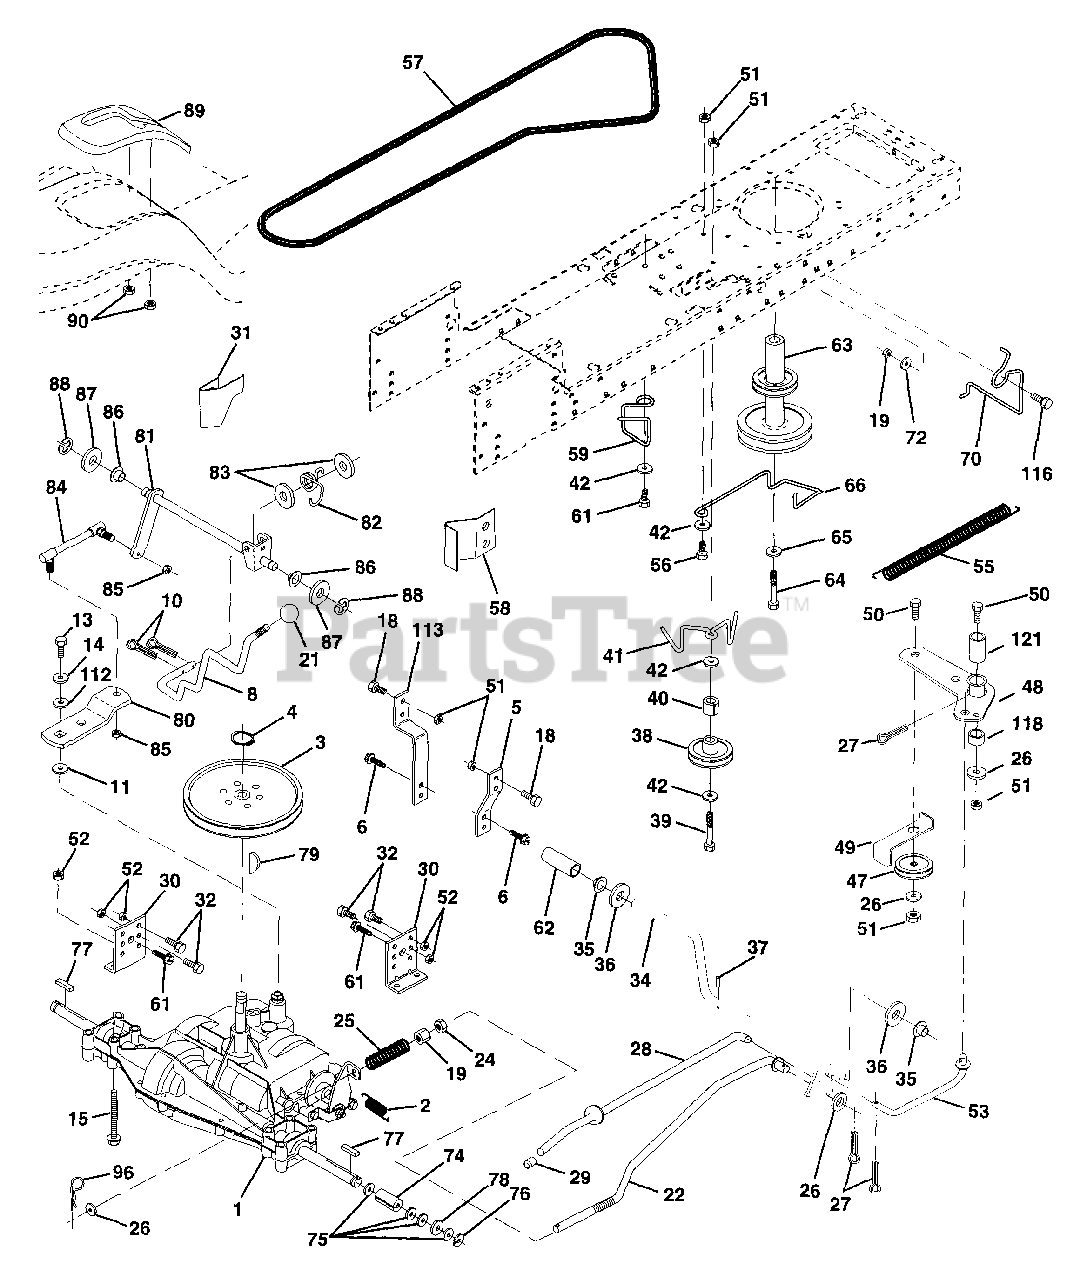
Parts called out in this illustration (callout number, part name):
2	Spring Return Brake T/a Zinc
3	Pulley Transaxle 18" tires
4	Ring Retainer # 5100-62
5	Strap Torque 30 Degrees
6	Screw Thdrol 5/1 6-18 X 3/4 TYT
8	Rod Shifter
10	Pin Cotter 1/8 X 1 Cad
11	Washer Plate Shf 388 Sq Hole
13	Bolt 1/4-28 Unf Gr 8 W/Patch
14	Washer Lock Hvy Helical 1/4
15	Bolt Hex 5/16-18 Gr. 5
18	Bolt, Fin Hex 3/8-16 UNC x 1 Gr. 5
19	Nut Lock 3/8-16 Unc
22	Rod Brake Blk Zinc 26 840
24	Nut Hex Jam 3/8-16 Unc
25	Spring Rod Brake 2 00 Zinc
26	Washer 13/32 X 13/16 X 16 Ga
27	Pin Cotter 1/8 X 3/4 Cad
28	Rod Brake Parking LT/YT
29	Cap Brake Parking Black
30	Bracket Mtg Transaxle
31	Keeper Belt LH LT 14 Ga
32	Bolt Hex Hd 5/16-18 unc X 3/4
34	Shaft Asm Pedal Foot
35	Bearing Nylon Blk 629 Id
36	Washer 21/32 X 1 X 16 Ga
37	Pin Roll 3/16 X 1"
38	Pulley Idler Flat
39	Bolt Fin Hex 3/8-16unc X 2-3/4
40	Spacer Split 395 X 59 Bzp
41	Keeper Belt Retainer Idler Foolproof
42	Washer 13/32 X 13/16 X 12 Ga
47	Pulley Idler V Groove Plastic
48	Bellcrank Asm
49	Retainer Belt Style Spring
50	Bolt Hex Hd 3/8-16unc X 1-1/2
51	Nut Crownlock 3/8-16 Unc
52	Nut Crownlock 5/16-18 Unc
53	Link Clutch
55	Spring Return Clutch 6 75
56	Bolt Fin Hx 3/8-16 X 1/4
57	V-Belt Ground Drive 95 25
58	Keeper Belt RH LT Pnt/zinc 16g
59	Keeper Belt Span Ctr
61	Screw Thdrol 3/8-16 x 3/4 Ty-tt
62	Cover Pedal Blk Round
63	Engine Pulley LT/YT
64	Bolt Hex
65	Washer Lock Hvy Hlcl Spr 7/16
66	Keeper Belt Engine Foolproof
70	Guide Belt Mower Drive RH
72	Washer 13/32 X 1-1/4 X 12 Ga
74	Spacer Axle
75	Washer 25/32 X 1 1/4 X 16 Ga
76	E-ring #5133-75
77	Key Square 2 0 X 1845/1865
78	Washer 25/32 X 1-5/8 X 16 Ga
79	Key Woodruff #9 3/16 x 3/4
81	Shaft Asm Cross 20"t
82	Spring Torsion T/a
83	Washer 17/32 X 3/4 X 16 Ga
84	Rod Shift
85	Nut Lock Center 1/4 - 28 FNTHD
86	Bushing Rod Strg 629/632 Id
87	Washer 21/32 X 1-1/4 X 16 Ga
88	Ring Klip #5304-62
89	Console Shift STLT
90	Nut Self-thd Wsh-hd 1/4 Zinc
96	Retainer Spring 1"
112	Washer 9/32 x 3/4 x 10 Ga.
113	Strap Torque LT
116	Bolt Rdhd Sq Neck 3/8-16 x 1.25
118	Spacer Bellcrank
121	Nyliner Clutching STL
